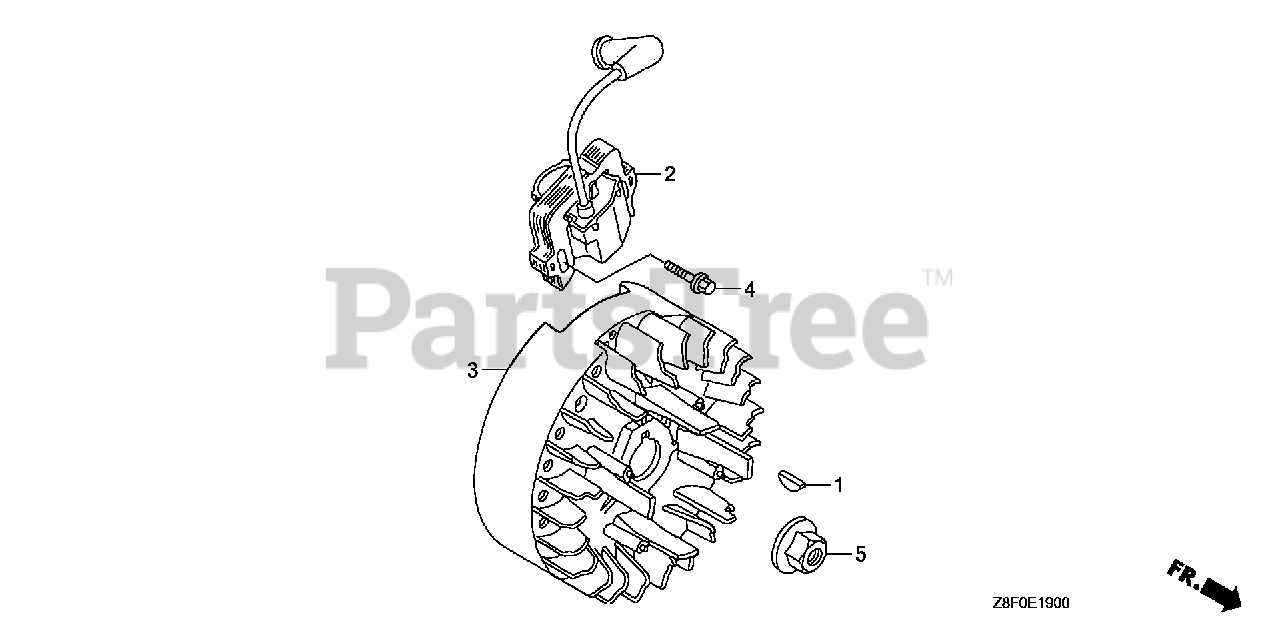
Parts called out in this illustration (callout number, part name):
1	KEY, SPECIAL WOODRUFF (25X18)
2	COIL ASSY., IGNITION (USE FOR F/W OF TEC) (TEC) Use up to Engine SN 3747197.
3	FLYWHEEL COMP. (TEC) (USE FOR IGN. COIL OF TEC) Use up to Engine SN 3747197.
4	BOLT, FLANGE (6X21)
4	BOLT, FLANGE (6X20) (CT200)
5	NUT, SPECIAL (14MM)
